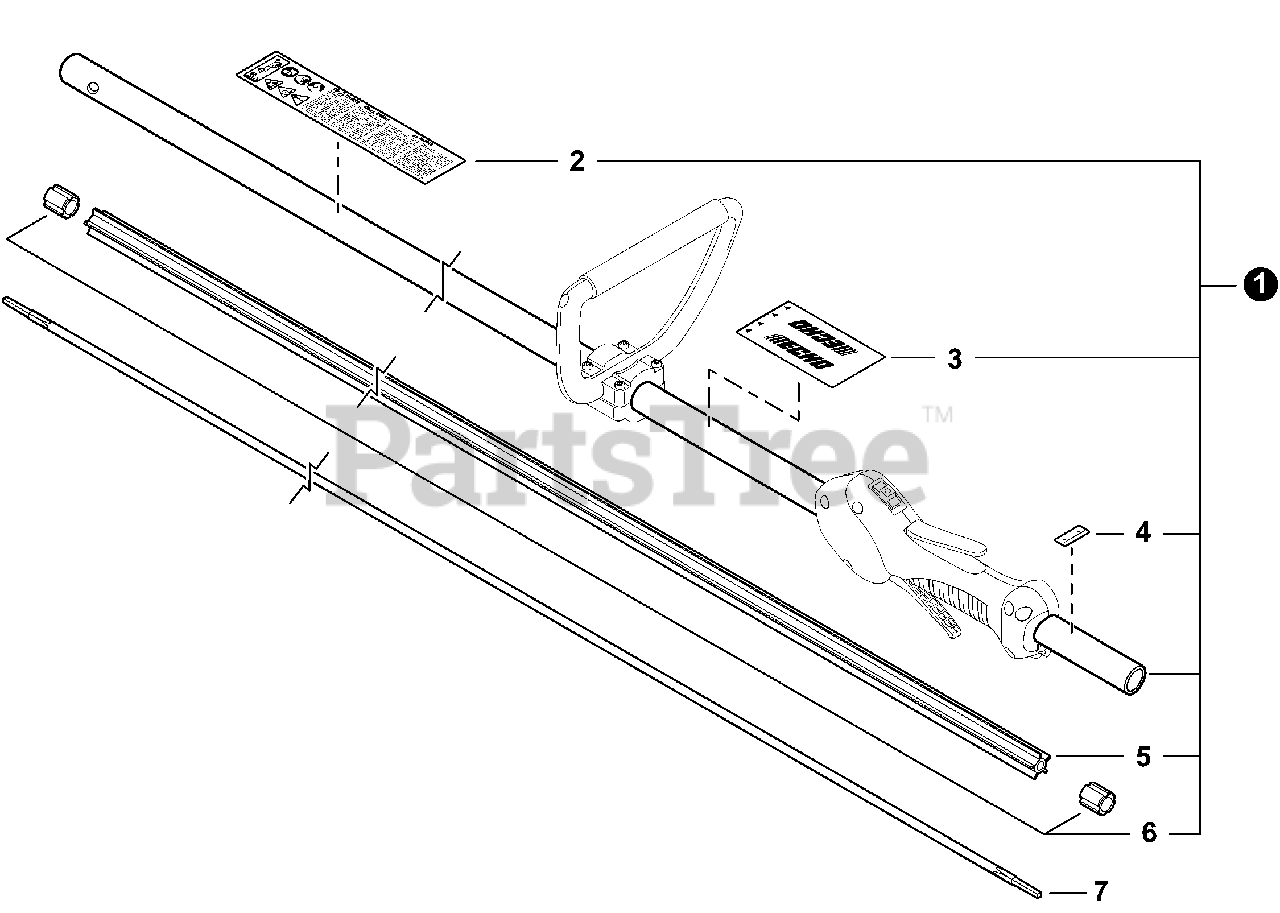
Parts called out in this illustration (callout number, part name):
1	MAIN PIPE ASSY
2	LABEL, CAUTION
3	LABEL, HANDLE LOCATION
4	LABEL - ALIGNMENT
5	LINER, FLEXIBLE 21.6×1420
7	DRIVESHAFT - FLEXIBLE
